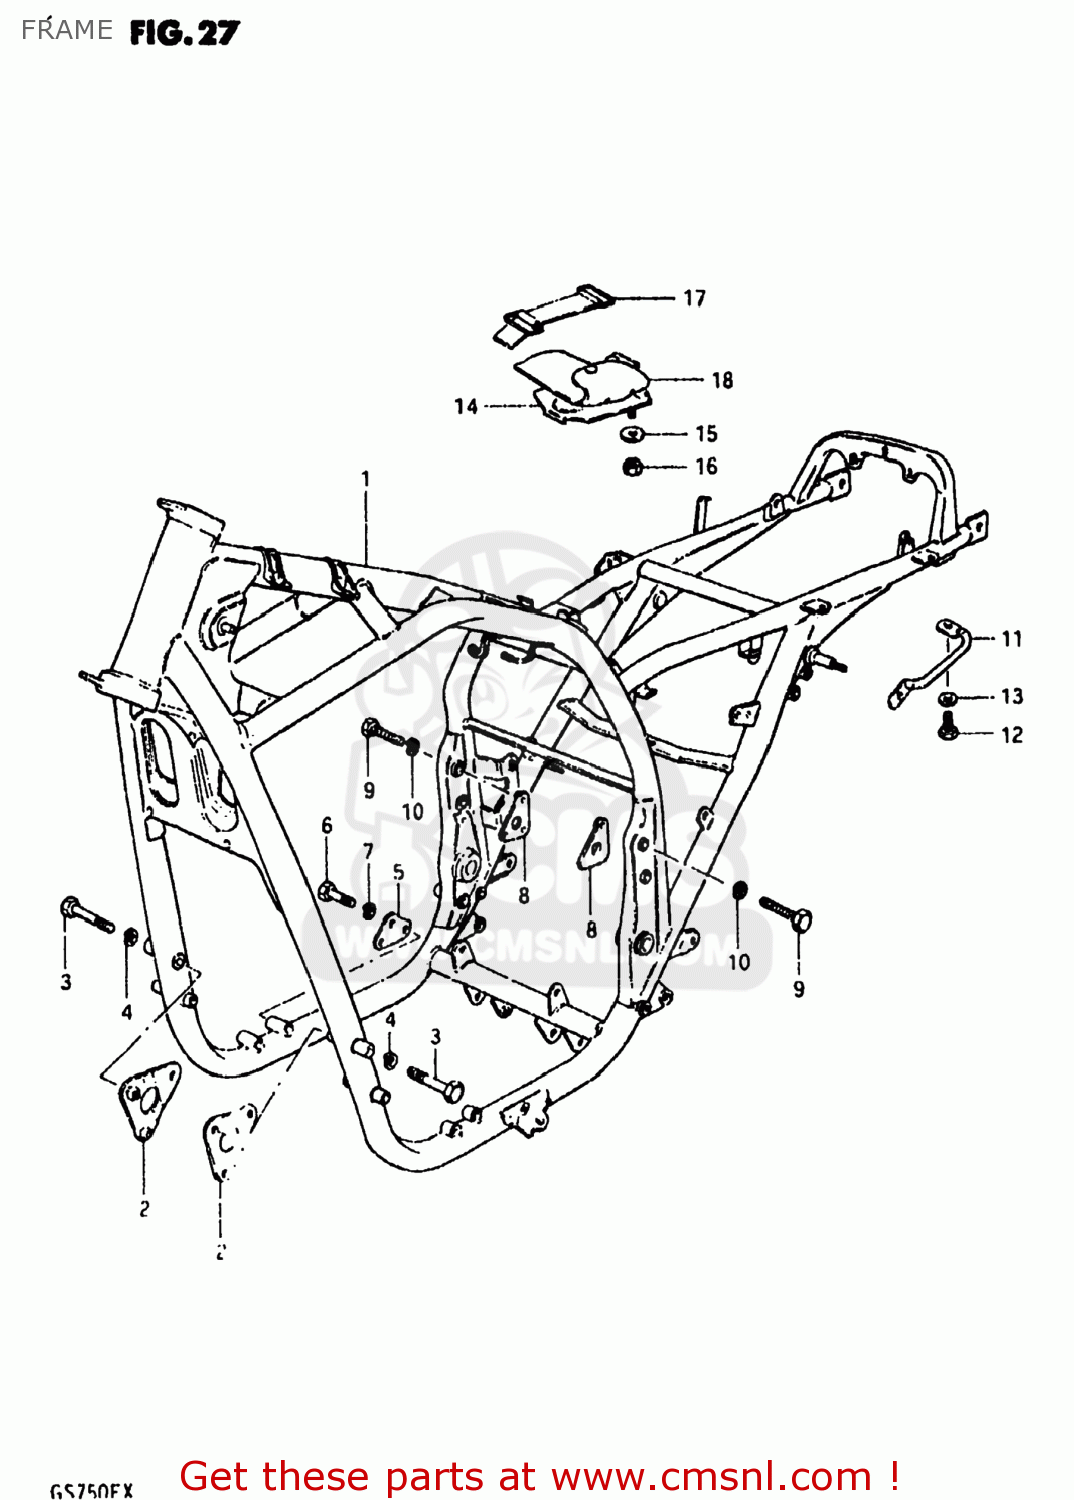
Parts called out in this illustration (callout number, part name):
1	FRAME
2	PLATE,ENG MTG NO.1
3	BOLT
4	LOCK WASHER
5	PLATE,ENGINE MOUNTING
6	BOLT
7	LOCK WASHER
8	PLATE,ENGINE MOUNTING
9	BOLT
10	LOCK WASHER
11	GRIP,FRAME
12	BOLT
13	WASHER
14	HOLDER,TOOL
15	WASHER
16	NUT
17	BAND
18	TOOL SET
